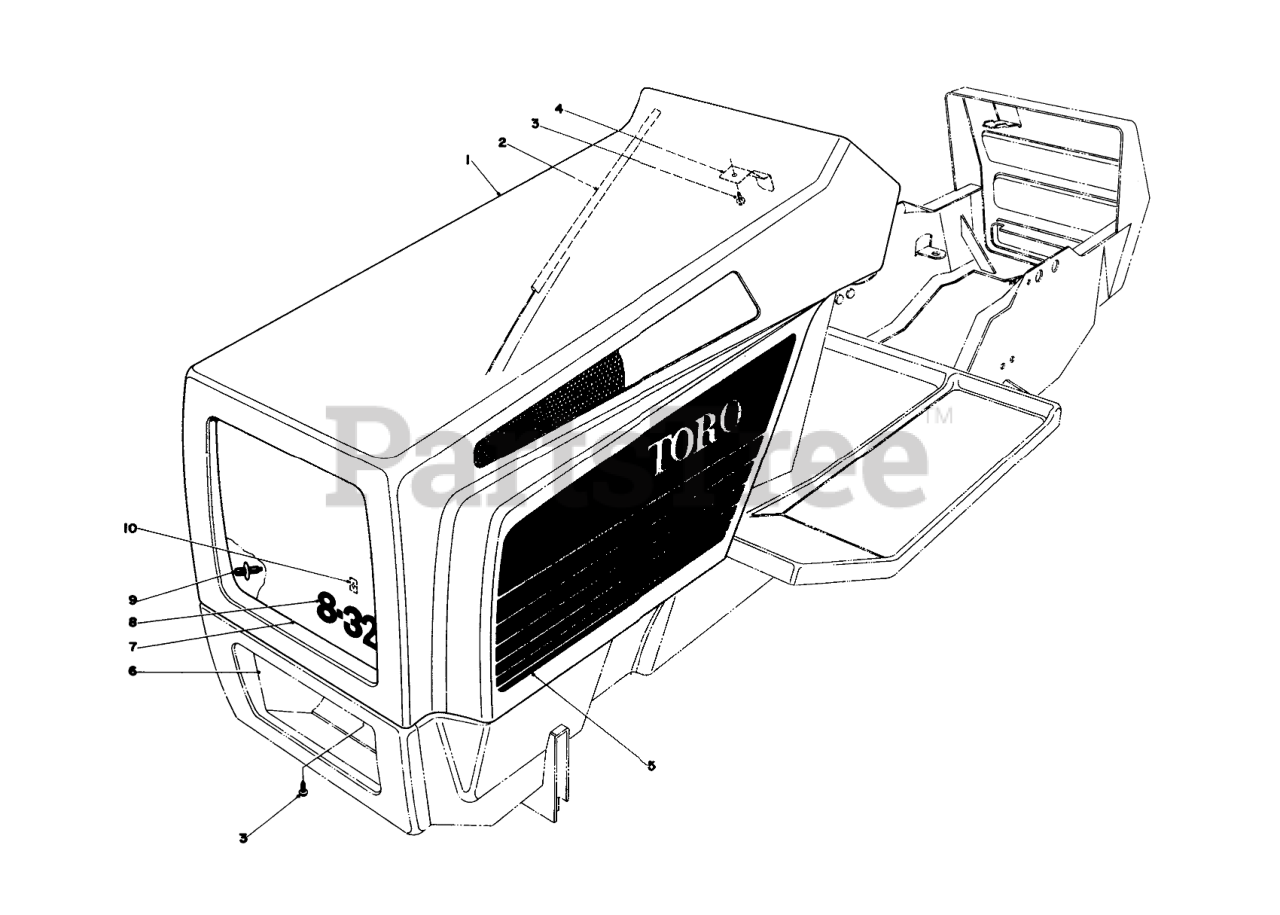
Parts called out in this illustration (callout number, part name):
1	Hood Assy. (Incl. Ref. #5)
2	RUBBER EXT SEAL
3	SCREW-HWHTF
4	SPRING LATCH
5	Decal Hood LH.
6	LOWER GRILLE
7	HOOD GRILLE
8	Nameplate Grille
9	HINGE BRKT STUD
